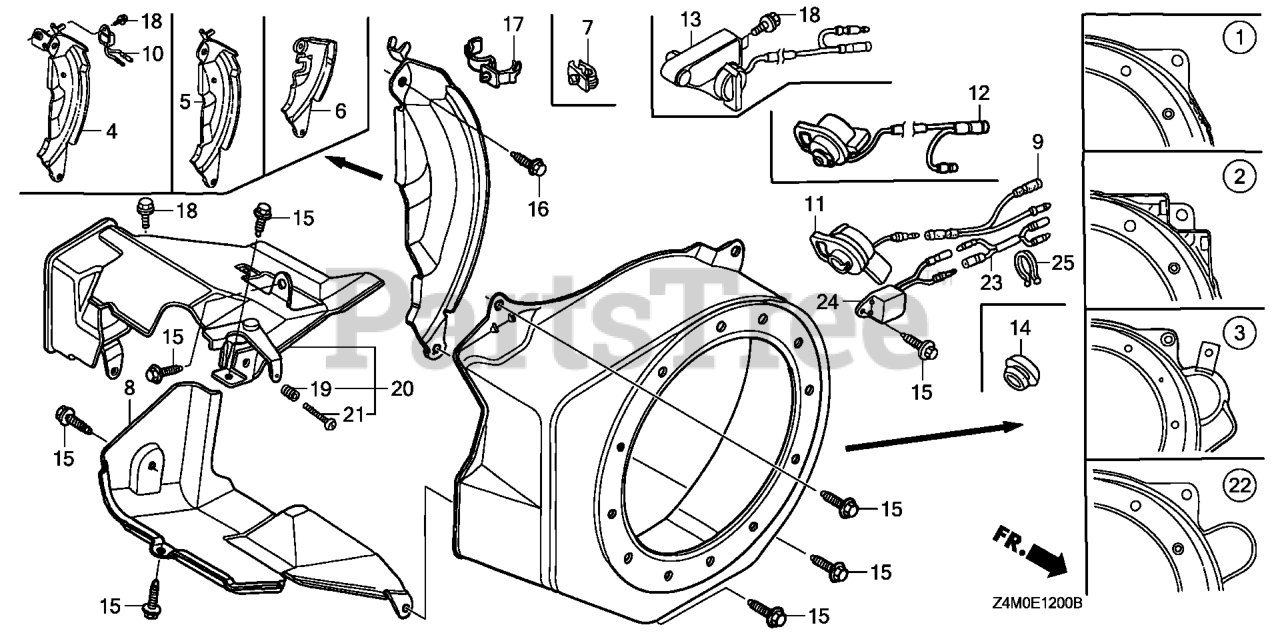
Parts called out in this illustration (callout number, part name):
1	COVER, FAN *R280* (POWER RED)
1	COVER, FAN *NH1* (BLACK)
5	PLATE, SIDE (STD)
11	SWITCH ASSY., ENGINE STOP (TOYO DENSO)
11	SWITCH ASSY., ENGINE STOP (MINDA)
15	BOLT, FLANGE (6X12) (CT200)
16	BOLT, FLANGE (6X20) (CT200)
